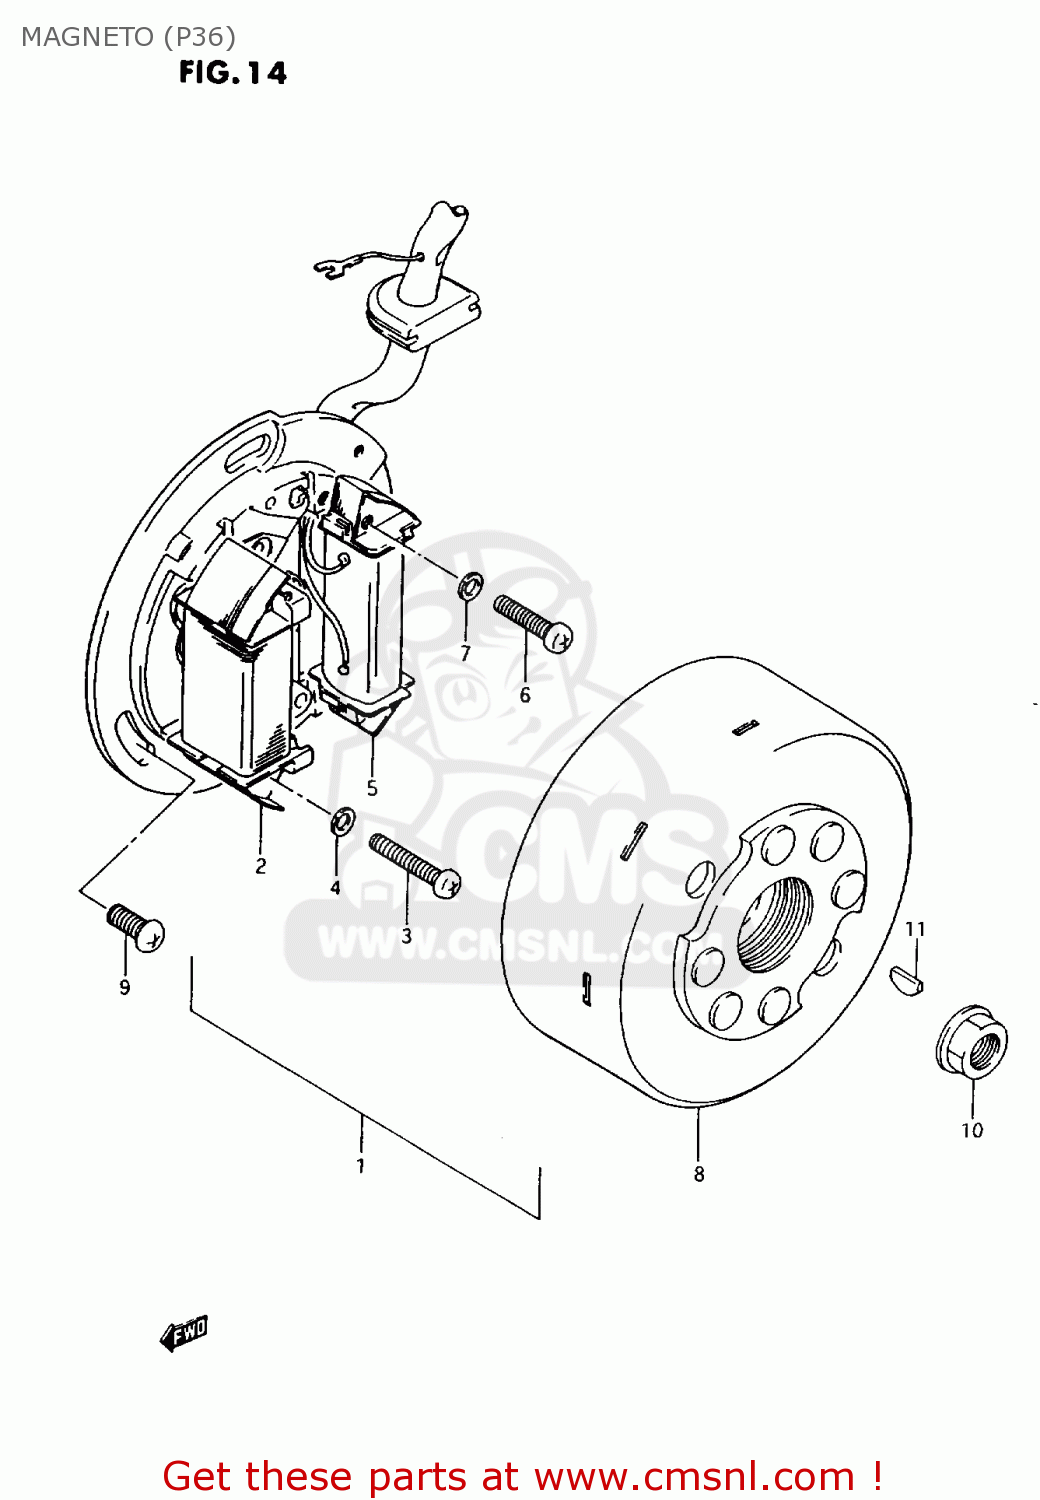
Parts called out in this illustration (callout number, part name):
1	STATOR ASSY
2	COIL, LIGHTING
3	SCREW
4	WASHER,LOCK
5	COIL, PRIMARY
6	SCREW
7	WASHER,LOCK
8	ROTOR, FRYWHEEL
9	SCREW 5X12
10	NUT
11	KEY
